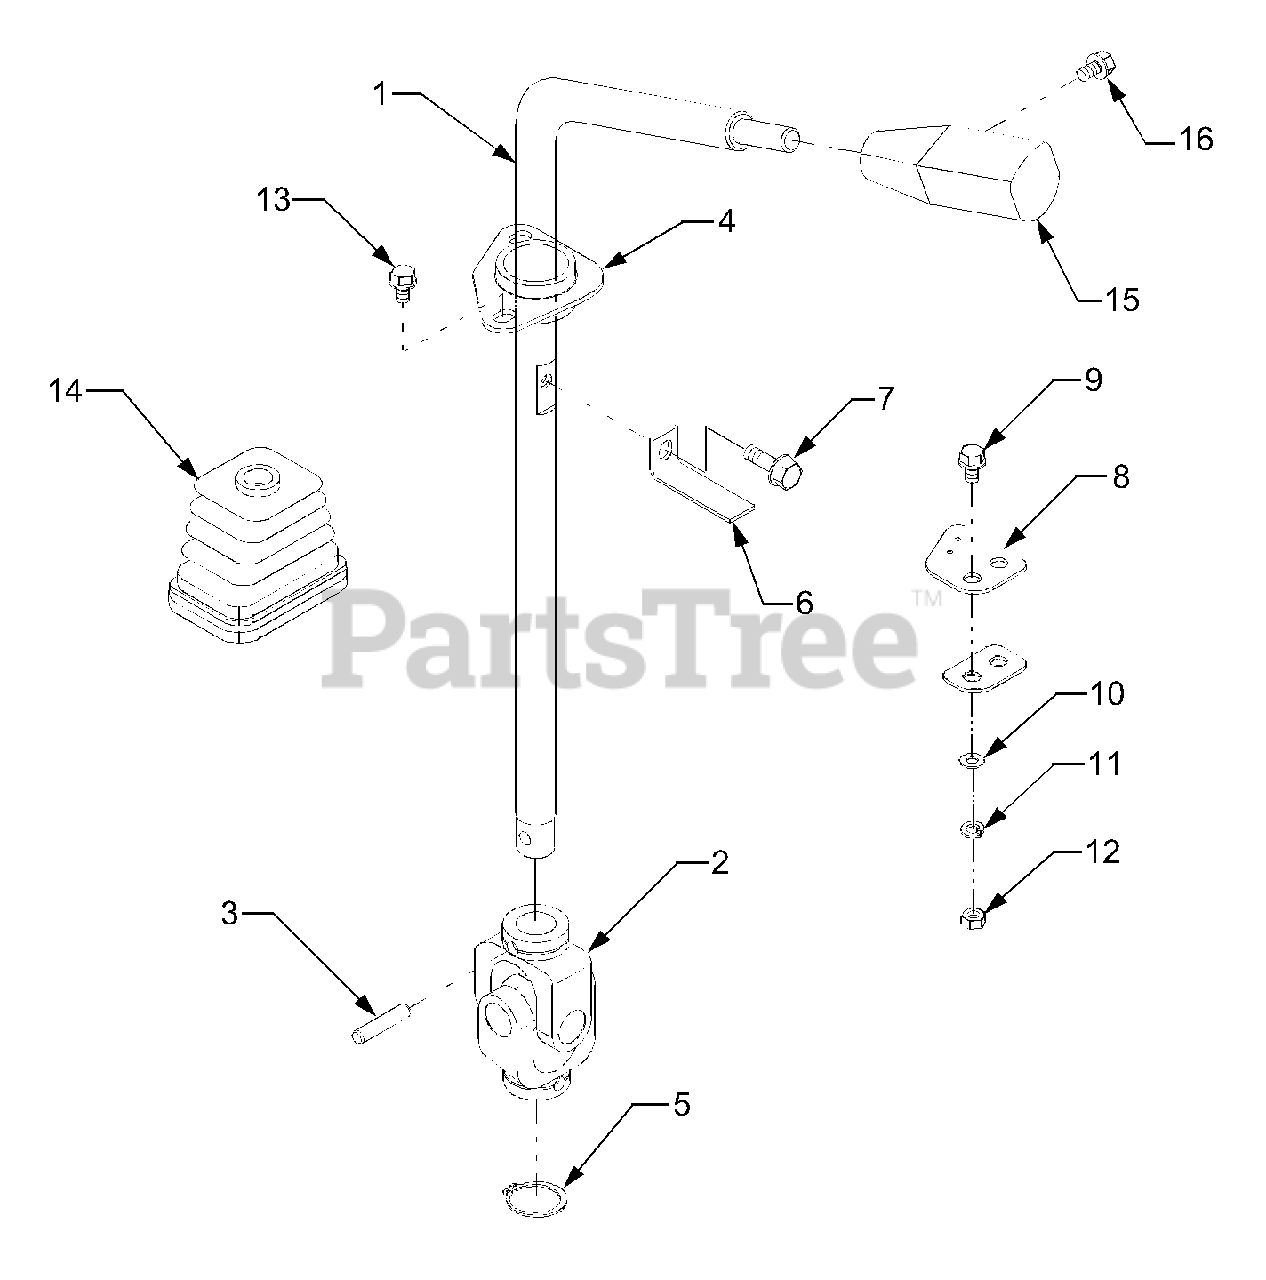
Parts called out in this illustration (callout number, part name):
1	Lever, Shuttle
2	Joint, Universal
3	Pin, Straight
4	Flange, Bearing
5	Cir-clip, External
6	Bracket, Switch
10	Washer, Plain
11	Washer, Spring
